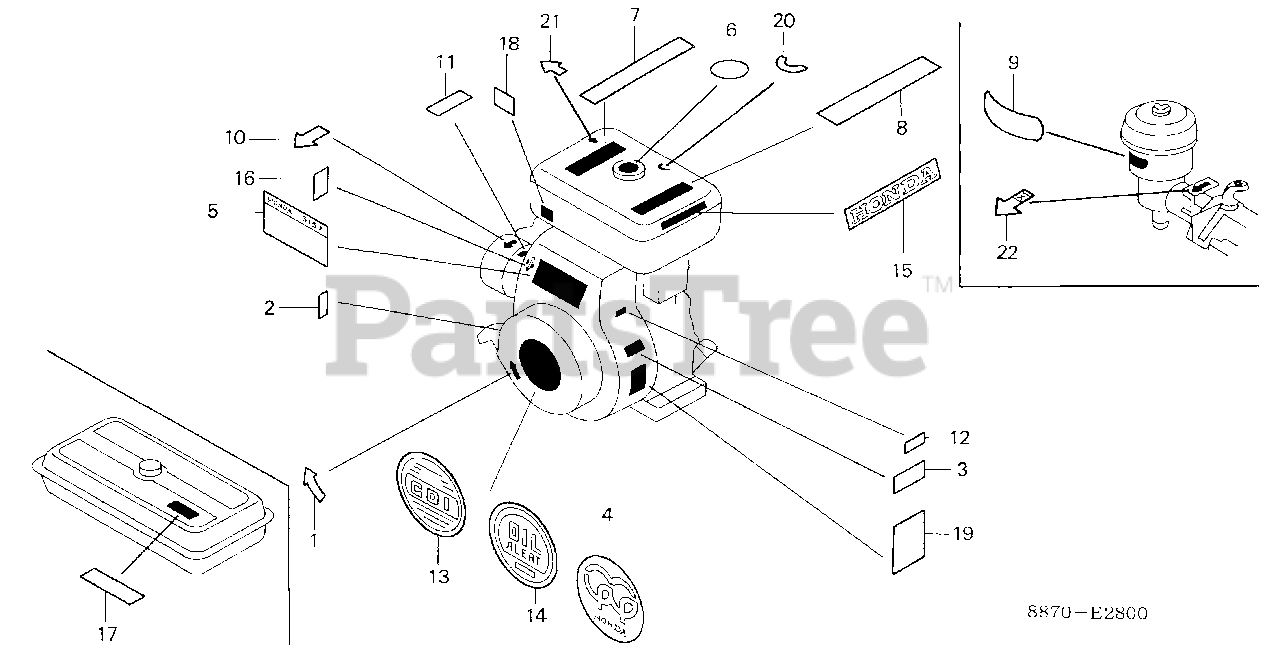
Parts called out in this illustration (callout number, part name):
5	EMBLEM (ENGLISH/FRENCH)(SPANISH) (NOT AVAILABLE)
6	MARK, CAUTION
7	MARK, CAUTION (ENGLISH/FRENCH/SPANISH)
14	LABEL, OIL ALERT
19	MARK, OIL CAUTION
20	MARK V, CAUTION
20	MARK, CHOKE
